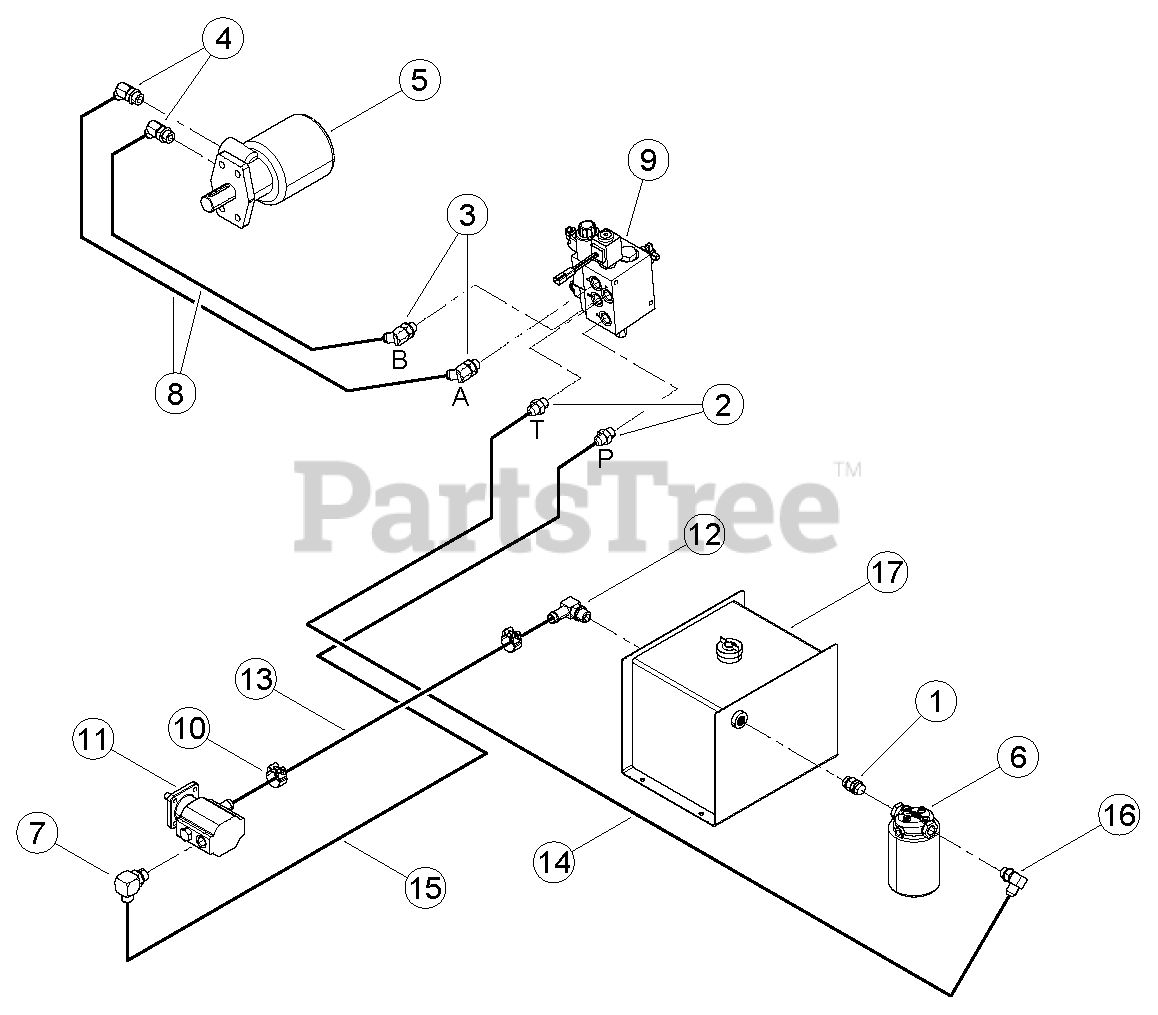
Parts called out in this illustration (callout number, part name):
1	ADAPTER, -8 MORING / -8 MORING ADJ
2	ADAPTER, -8 MORING / -8 MJIC
3	ADAPTER, -8 MORB / -8 MJIC 45 DEG.
4	ADAPTER, -10 MORING / -8 MJIC 45 DEG.
5	MOTOR, 45 CU. IN. HYDRAULIC
6	FILTER, SPIN-ON
7	ADAPTER, -10 MORING / -10 MJIC 90 DEG.
8	HOSE, .375 X 36 -8 FMJIC / -8 FMJIC
9	ASSEMBLY, CHIPPER VALVE (SEE VALVE ASSEMBLY FOR SERVICE PARTS)
10	CLAMP, 1-5/32 TO 7/32 OD RANGE T-BOLT
11	PUMP, 2 STAGE CW HI/LO 0.605 DISP.
12	ADAPTER, -10 MORING / .75 90 DEG.
13	HOSE, .75 ID. X 38 IN. 100R4 HYD.
14	HOSE, .50 X 84 -8 FMJIC / -8 FMJIC
15	HOSE, .50 X 66 -8 FMJIC / -10 FMJIC 90 DEG.
16	ADAPTER, -8 MORING / -8 MJIC 90 DEG.
17	WELDMENT, TANK HYDRAULIC 3.25 GAL.
